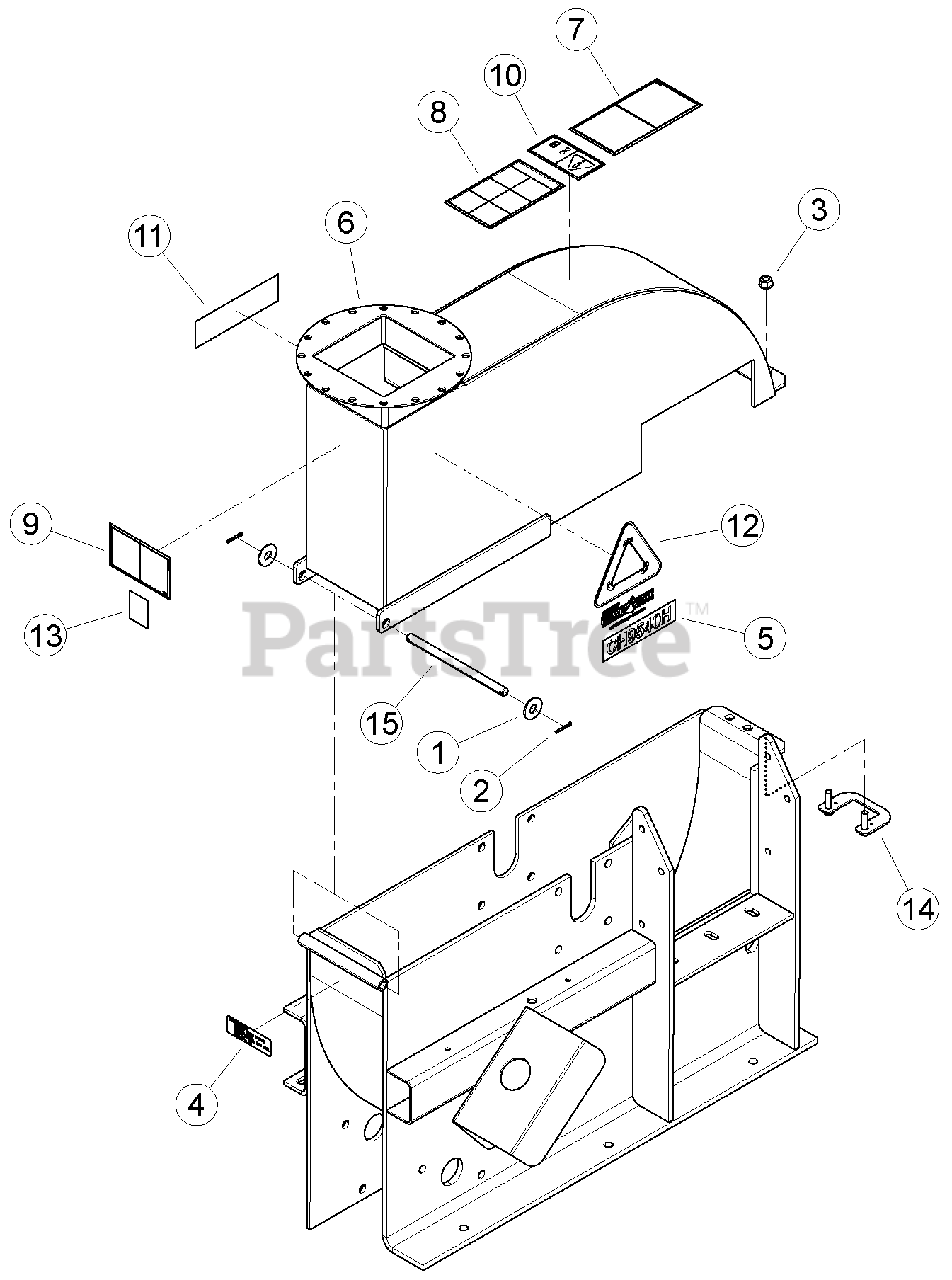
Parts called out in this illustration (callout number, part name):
1	WASHER, 1/2" FLAT ZP
2	PIN, 1/8 X 1.00 ZP COTTER
3	NUT, 3/8-16 NYLOCK FLANGE
4	DECAL, ATLANTIC BRIDGE LTD INFO (CE COMPLIANT ONLY)
5	DECAL, MODEL CH9540H
6	ASSEMBLY, CHIPPER COVER W/ DECALS
7	DECAL, KNIFE ACCESS ISO
8	DECAL, OPERATING INSTRUCTIONS ISO
9	DECAL, DISCHARGE ISO
10	DECAL, MAINTENANCE ISO
11	DECAL, ECHO BEARCAT 6.82 X 1.90
12	DECAL, CHIP IT
13	DECAL, ECHO BEARCAT QR CODE
14	WELDMENT, CHIPPER HOUSING ACCESS
15	SHAFT, CHIPPER TOP PIVOT
